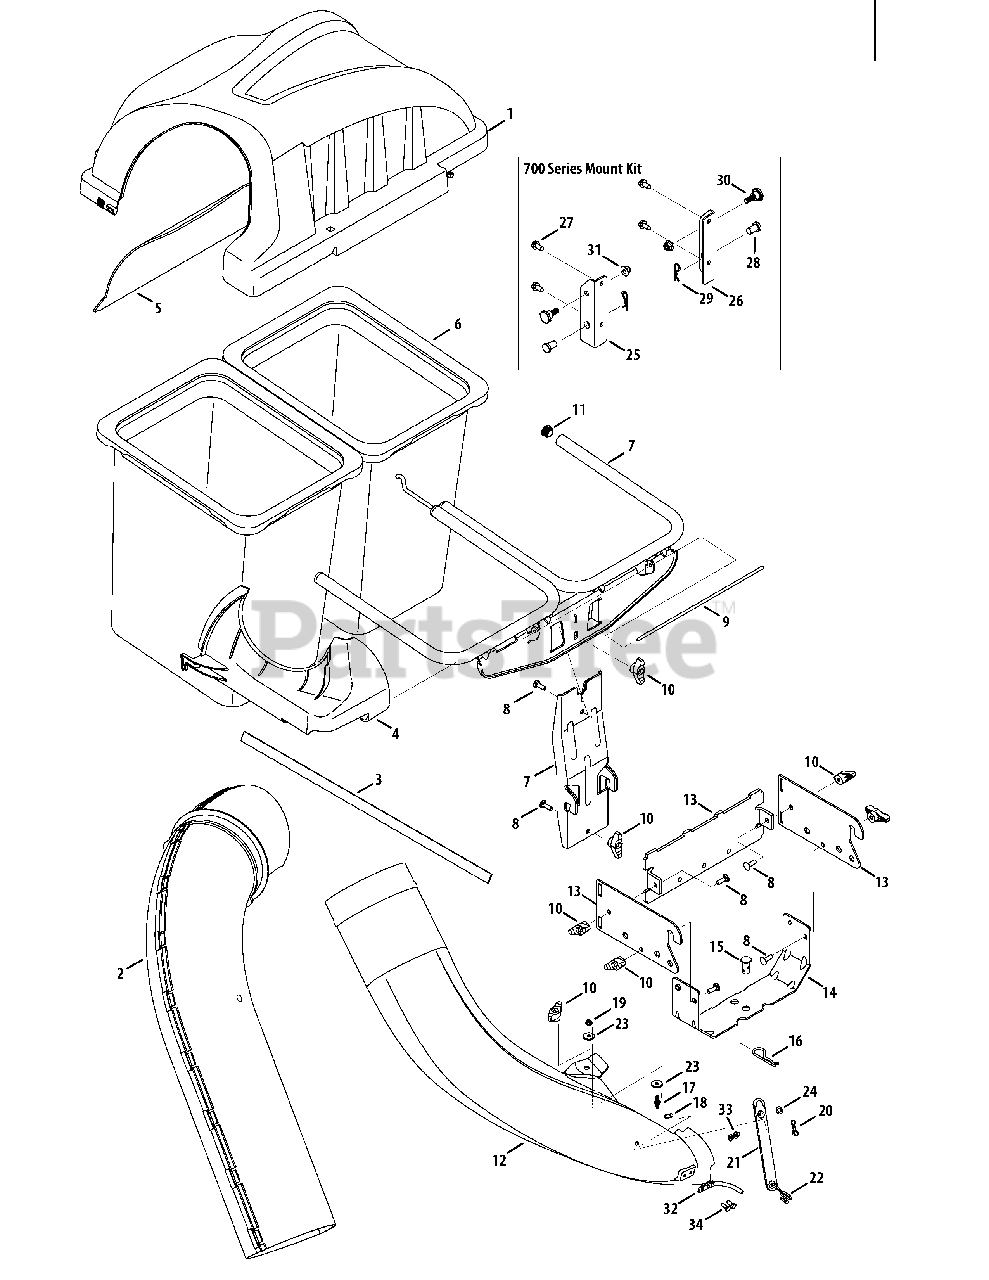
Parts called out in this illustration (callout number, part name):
1	Double Bagger Cover Assembly
2	Upper Chute Assembly
3	Self-Adhesive Foam Strip
4	Upper Chute Support
5	Bagger Cover Screen
6	Grass-bag Assembly
7	Vertical Support Bracket
8	Carriage Screw, 5/16-18 x 1.00"
9	Cover Hinge Pin
10	Wing Knob, 5/16-18
11	End Plug
12	Chute, Lower
13	Hitch Bracket Assembly
14	Universal Bracket Support
15	Clevis Pin, .62" Dia.
16	Internal Cotter Pin, .148 x 3.00
17	Attachment Pin
18	Clevis Pin, 5/16 x .75 Lg.
19	Flange Lock Nut, 1/4-20
20	Bow-Tie Cotter Pin, 72
21	Chute Strap, 6.00 Lg.
22	Torsion Spring Hook
23	Flat Washer, .265 x .938 x .120
24	Flat Washer, .344 x .620 x .033
25	Mounting Bracket, RH
26	Mounting Bracket, LH
27	Tap Screw, 5/16-18 x .750
28	Clevis Pin, .50 x .78 Lg.
29	Click Pin, .092 x 1.64 Lg.
30	Shoulder Screw, .625 x .412
31	Flange Lock Nut, 3/8-16
32	Chute Rod, Lower
33	Nut 1/4-20
34	Screw 1/4-20 X .62
